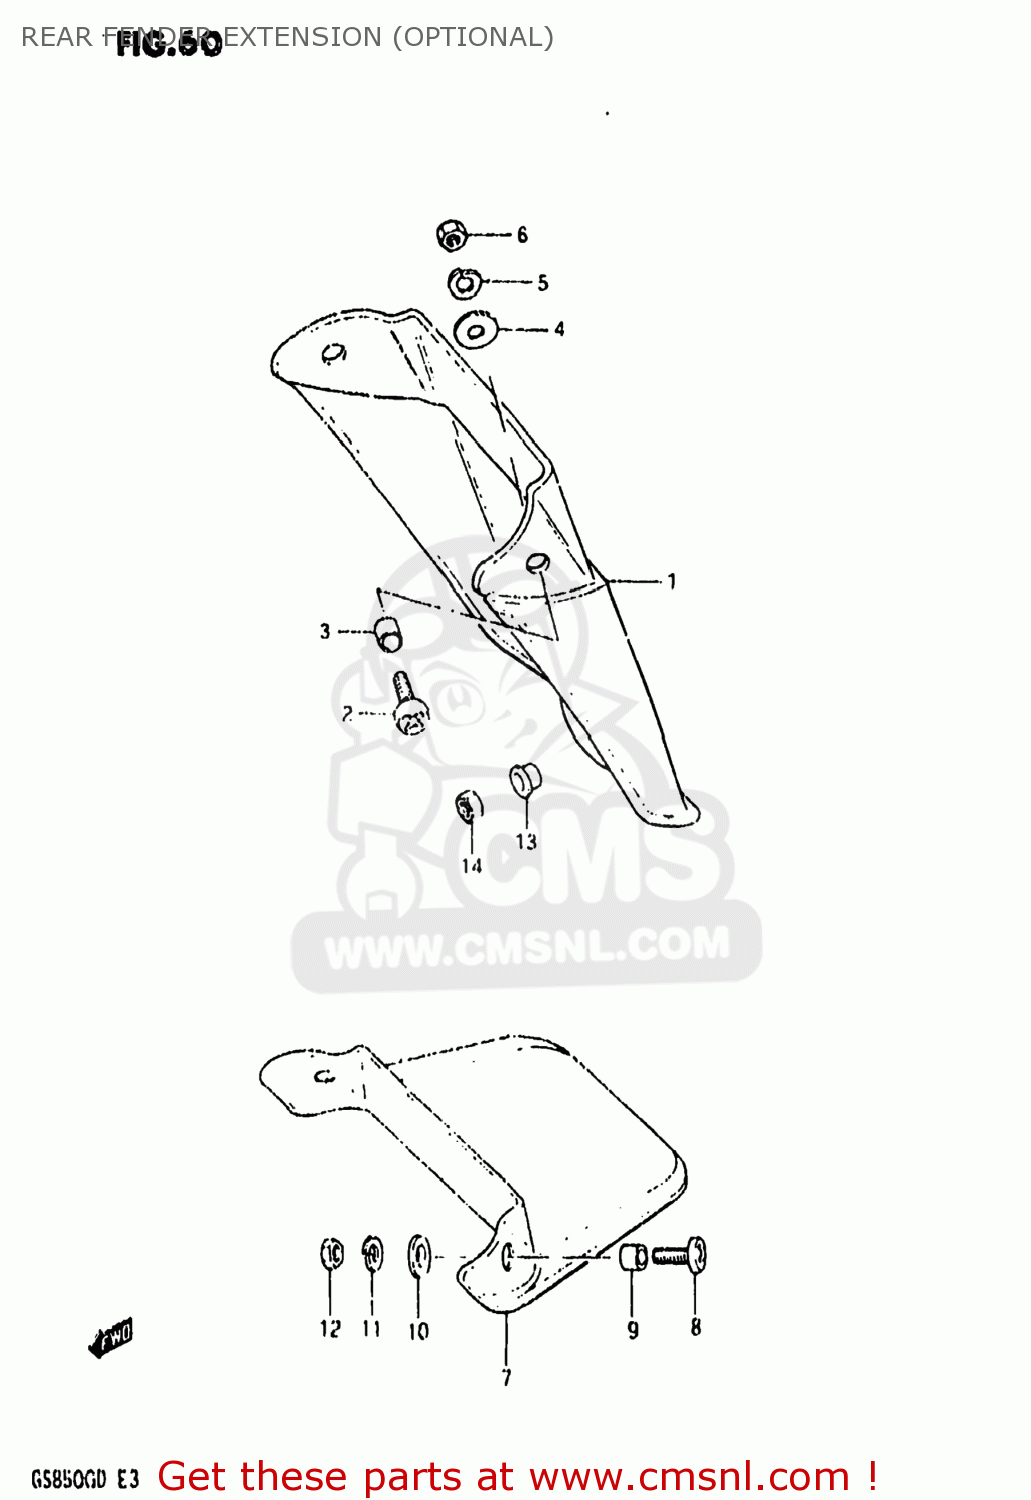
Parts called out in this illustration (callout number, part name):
1	EXTENSION,REAR FENDER
2	SCREW (6X15)
3	SPACER(6.2X8.3X5.7)
4	WASHER(6.5X18X1)
5	LOCK WASHER
6	NUT
7	EXTENSION,REAR FENDER
8	SCREW (6X15)
9	SPACER(6.2X8.3X5.7)
10	WASHER(6.5X18X1)
11	LOCK WASHER
12	NUT
13	SPACER
14	NUT
